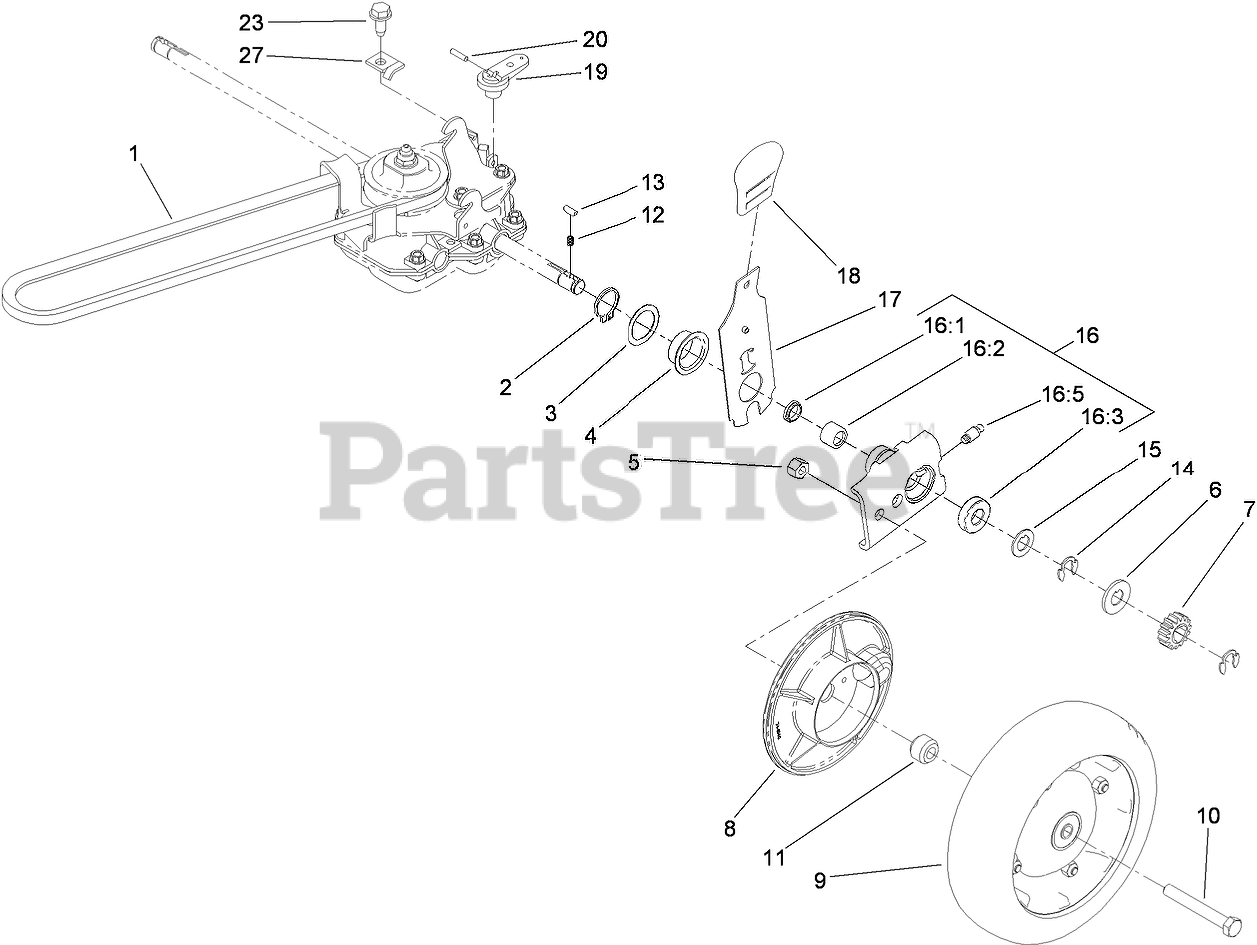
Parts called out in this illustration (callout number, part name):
1	V-BELT
2	RING-RETAINING
3	WASHER
4	CAP-END
5	NUT-LOCK, CONE
6	WASHER-THRUST, OUTER
7	GEAR-PINION
8	COVER-WHEEL
9	Wheel And Tire ASM
10	SCREW-HH
11	SPACER-COVER, WHEEL
12	SPRING-COMPRESSION
14	RING-RETAINING
15	WASHER-THRUST, OUTER
16	PIVOT ARM ASM
16:1	SEAL-OIL
16:2	BEARING-CAGED NEEDLE ROLLER
16:3	BEARING-WHEEL
17	REAR SPRING ARM ASM
18	KNOB-HOC
19	LEVER-SHIFT
20	PIN-COIL
23	SCREW-HWHTF
27	CLAMP-CABLE
